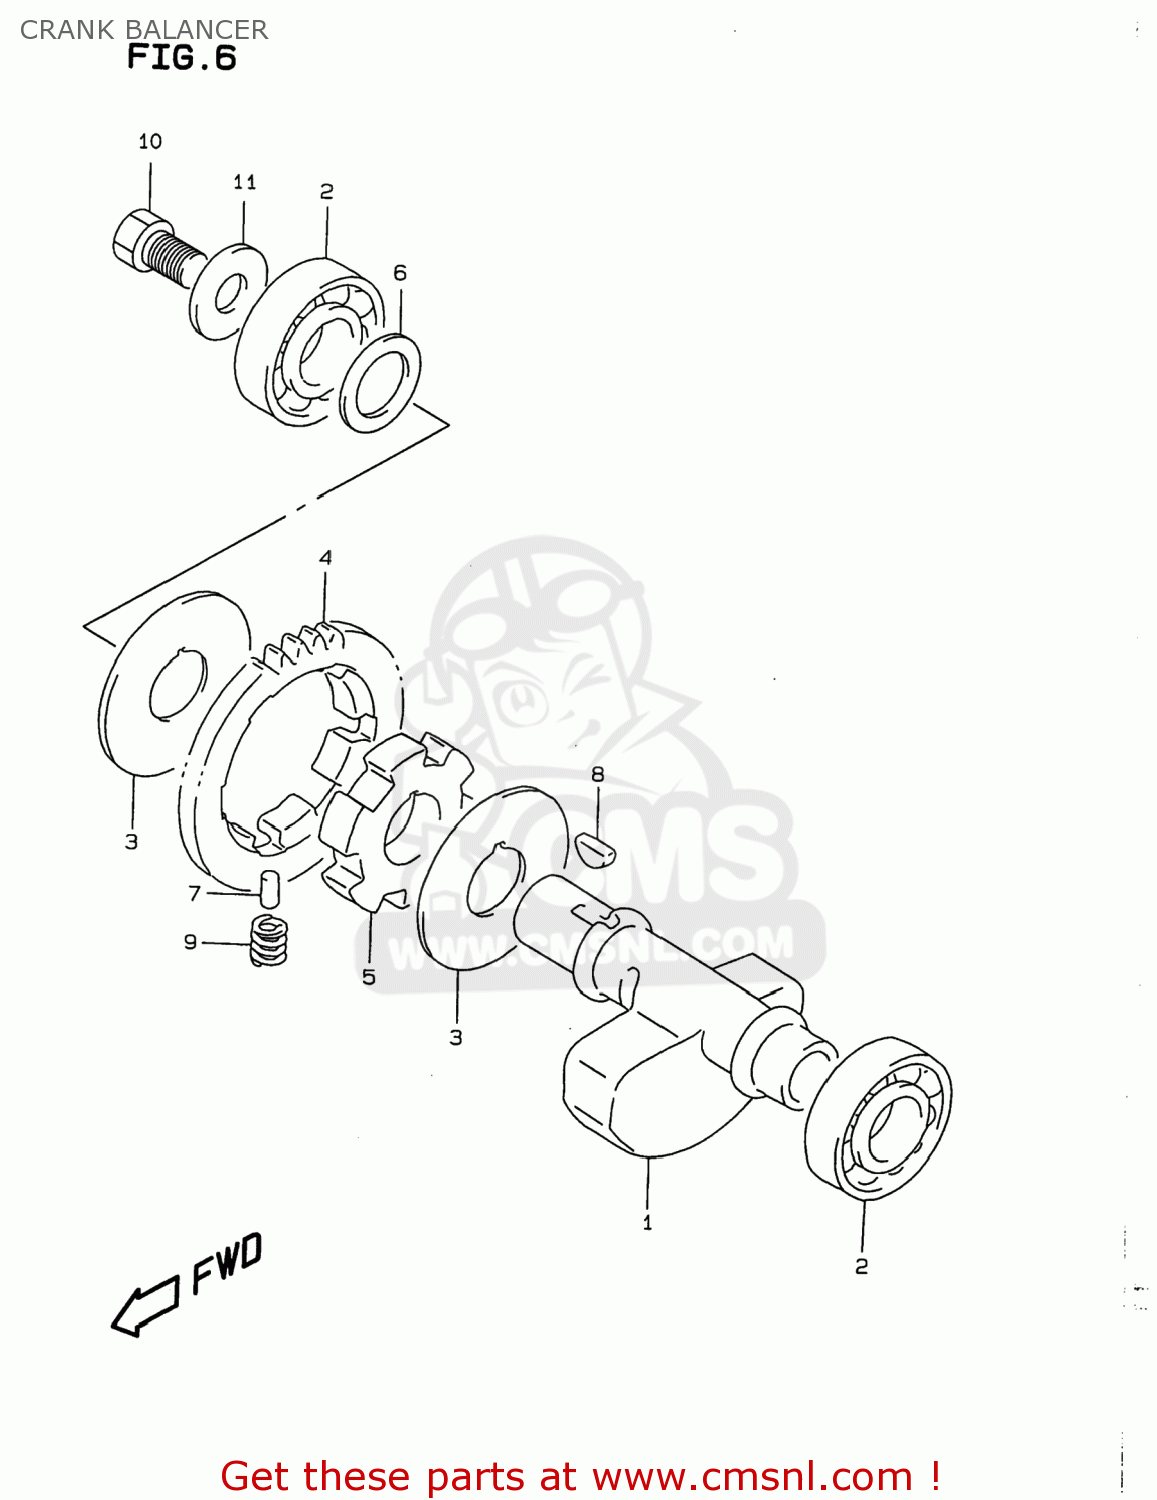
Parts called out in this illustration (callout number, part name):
1	SHAFT,CRANK BALANCER
2	BEARING(20X47X14)
3	WASHER
4	GEAR,CRANK BAL DRIVEN(NT:37)
5	RACE,CRK BAL DRIVEN GEAR INNER
6	SHIM(20X28X0.5)
7	PIN(4.5X9.5)
8	KEY
9	SPRING
10	BOLT
11	WASHER
